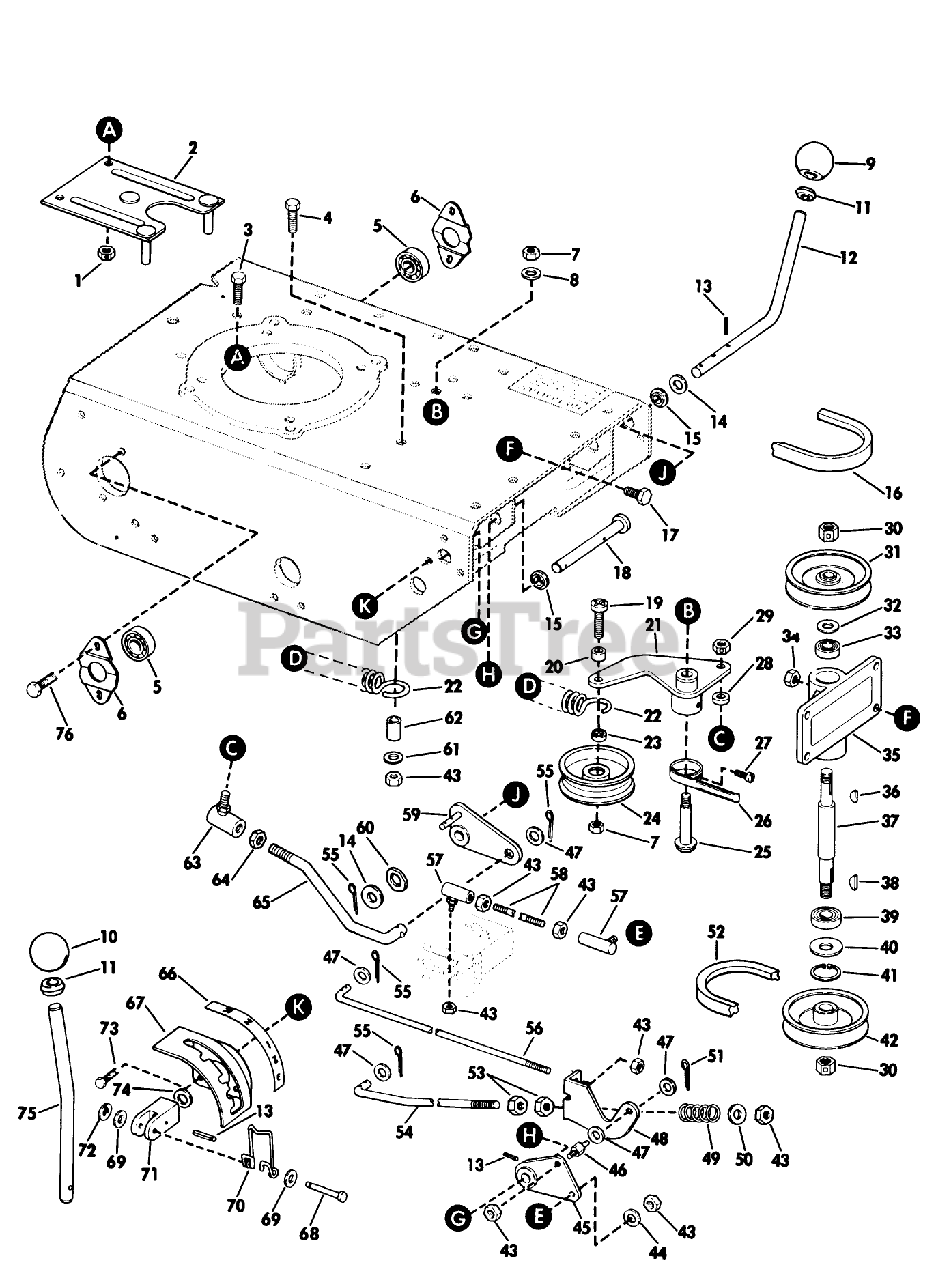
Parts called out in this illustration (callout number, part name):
7	LOCKNUT
43	STOP NUT
53	STOP NUT
55	Cotter Pin
